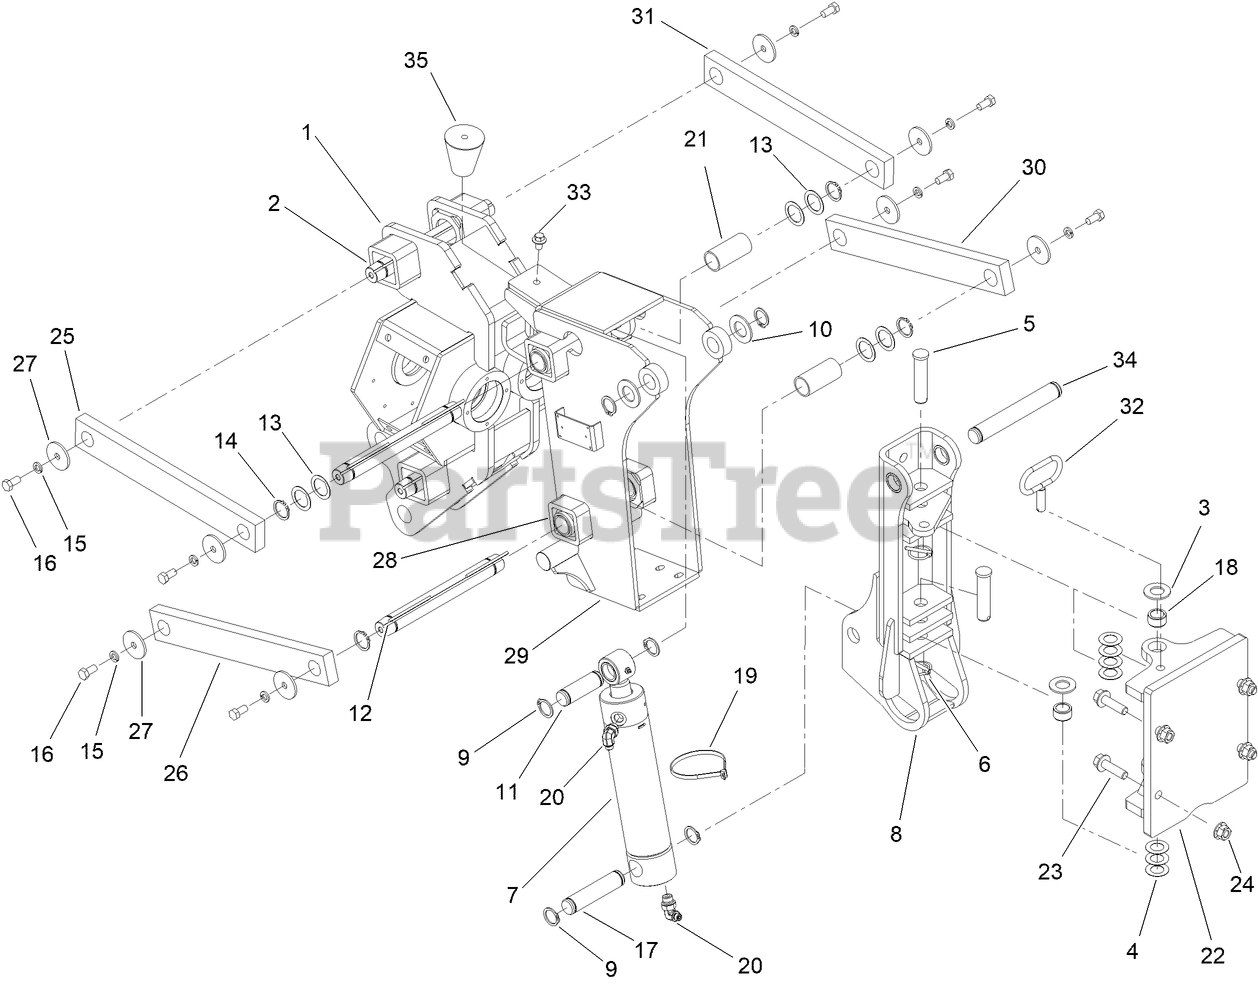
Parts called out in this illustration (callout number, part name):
1	VIBRATOR BOX - MACHINING
2	SHAFT-ARM, PLOW
3	WASHER-FLAT
4	WASHER-FLAT
5	PIN-PIVOT
6	KLIK PIN ASM
7	HYD CYLINDER ASM
8	PIVOT ASM
9	RING-RETAINING, EXTERNAL
10	WASHER-10 GAUGE
11	PIN-CLEVIS
12	KEY-SQUARE
13	SHIM-ARM
14	RING-RETAINING
15	WASHER-LOCK
16	SCREW-HH
17	PIN-CLEVIS
18	BUSHING-UPPER
19	TIE-CABLE
20	CONNECTOR (04O-08S90)
21	TUBE-SPACER
22	MOUNT PLATE
23	FLG BLT(5/8-NC X 2.25", GR 8)
24	FLG LOCKNUT (5/8-NC, GR G)
25	BAR - RH UPPER
26	BAR - RH LOWER
27	WASHER (1/2") ZP
28	JOINT-CT BD, J-8203
29	FRAME-LIFT, PLOW (WELDED)
30	BAR - LH LOWER
31	BAR - LH UPPER
32	LOCK-SWING
33	SCREW-HHF
34	PIN-LIFT
35	FEMALE BUMPER
